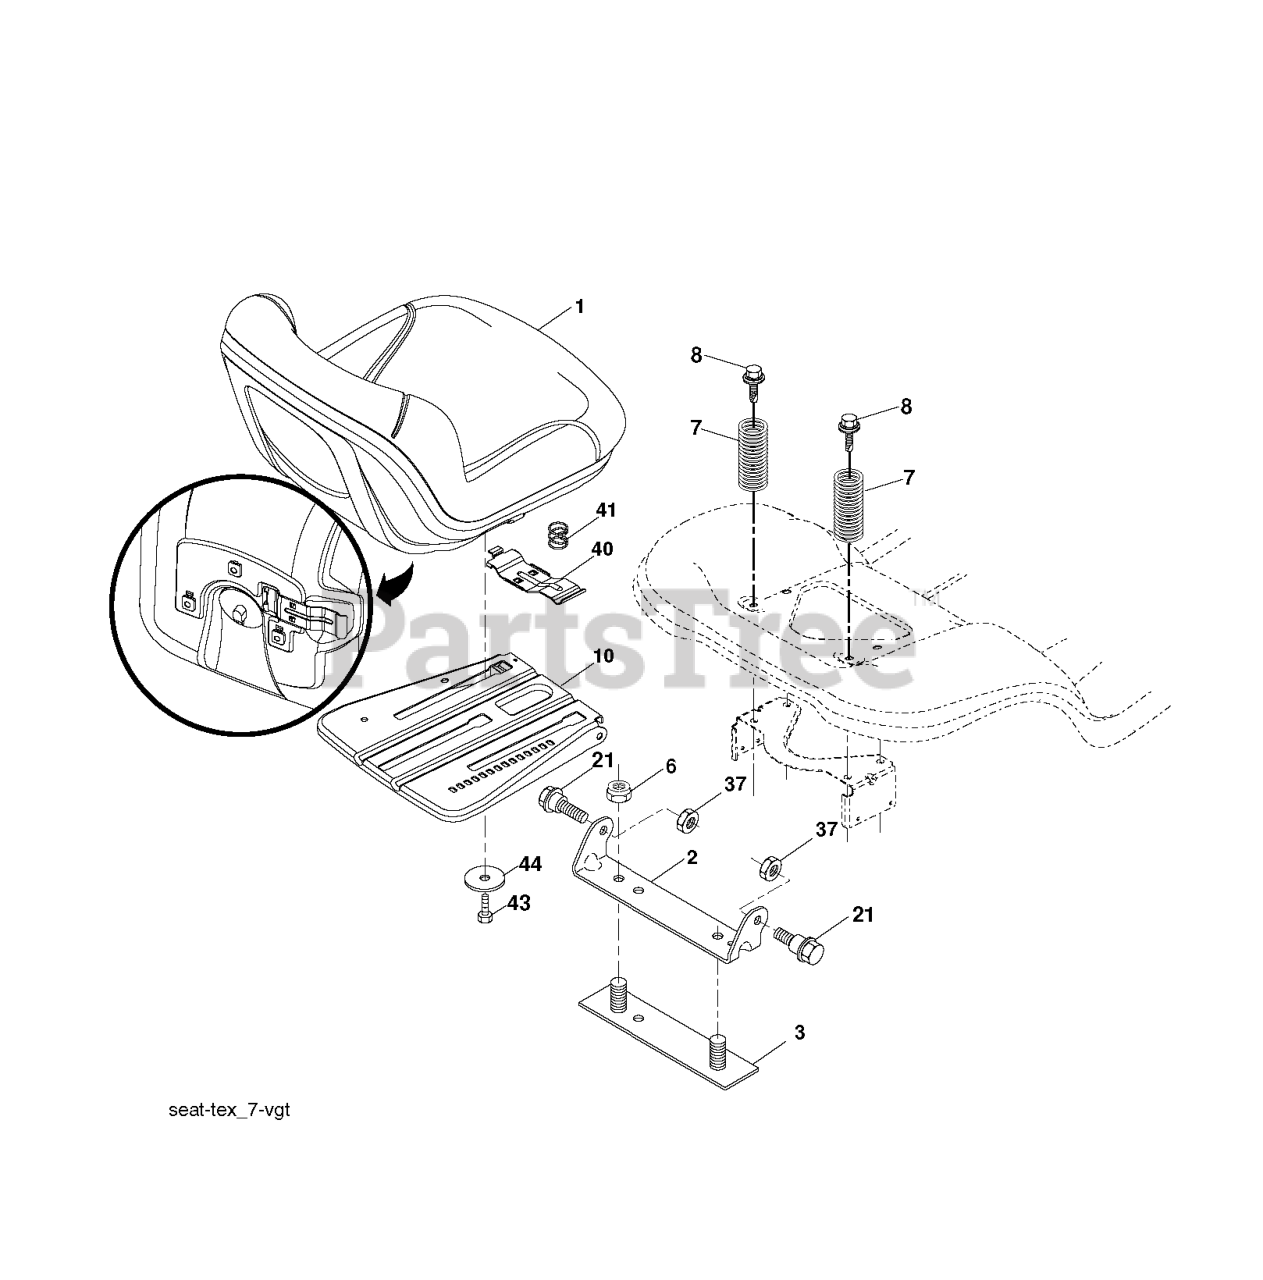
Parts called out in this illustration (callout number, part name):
1	SEAT.TH130.GRY.MILSCO.
2	BRKT.PIVOT.FENDER
3	STRAP
6	NUT
7	SPRING COMPRESSION
8	BOLT.5/16-18UNCX3/4 W/SEMS.BLK
10	PAN.ASM.SEAT.3PT
21	BOLT.SHOULDER.5/16-18
37	NUT.71038.31-18.HEX.NYLOCK
40	HANDLE.SLIDE.SEAT.TEX.BLACK
41	SPRING.LATCH.SEAT.TEX
42	WASHER.CUP.SEAT.
44	WASHER 13/32 X 2-3/8 X 12GA
